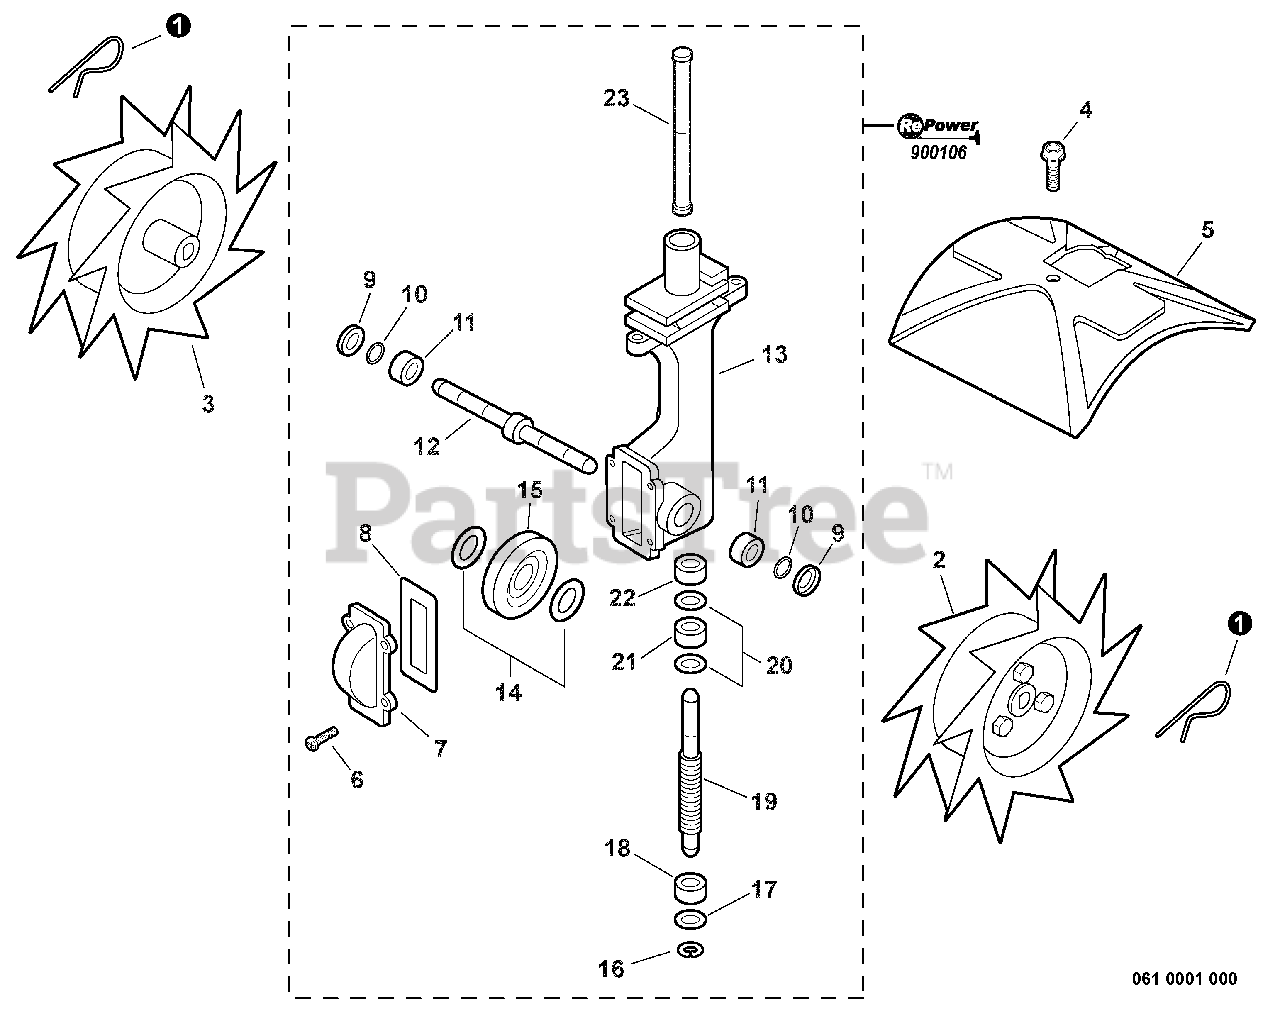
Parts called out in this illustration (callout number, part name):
1	PIN, SPLIT
2	ROTOR, CULTIVATOR - RIGHT
3	ROTOR, CULTIVATOR - LEFT
4	BOLT - 1/4 X 1/2"
5	SHIELD, ROTOR
6	SCREW -- TAPPING
7	COVER, GEAR CASE
8	GASKET, GEAR CASE
9	SEAL, BEARING
10	RING, RETAINING
12	SHAFT, TINE
13	CASE, GEAR
15	GEAR - WORM
16	RING, RETAINING - 15
18	BEARING, BALL
19	SHAFT, WORM
20	RACE, BEARING
21	BEARING, THRUST
22	BEARING, BALL
23	DRIVESHAFT
24	RePower GEAR CASE KIT
